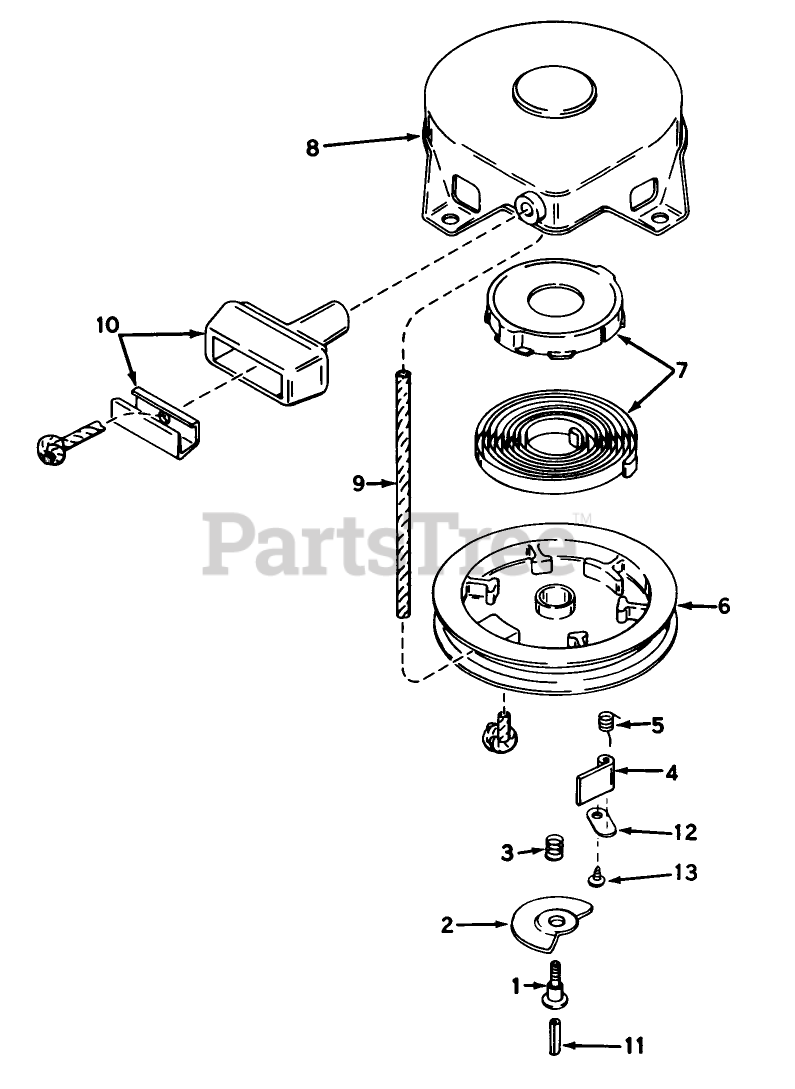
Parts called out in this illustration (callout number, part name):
1	Screw
2	Cam-Dog
3	Spring-Brake
4	Dog-Starter
5	Spring-Dog
6	Pulley
7	Spring Keeper Assy
8	STARTER HOUSING ASSY
9	Rope-Starter
10	Assy., Starter
11	Centering
12	Retainer-Dog
13	Screw
